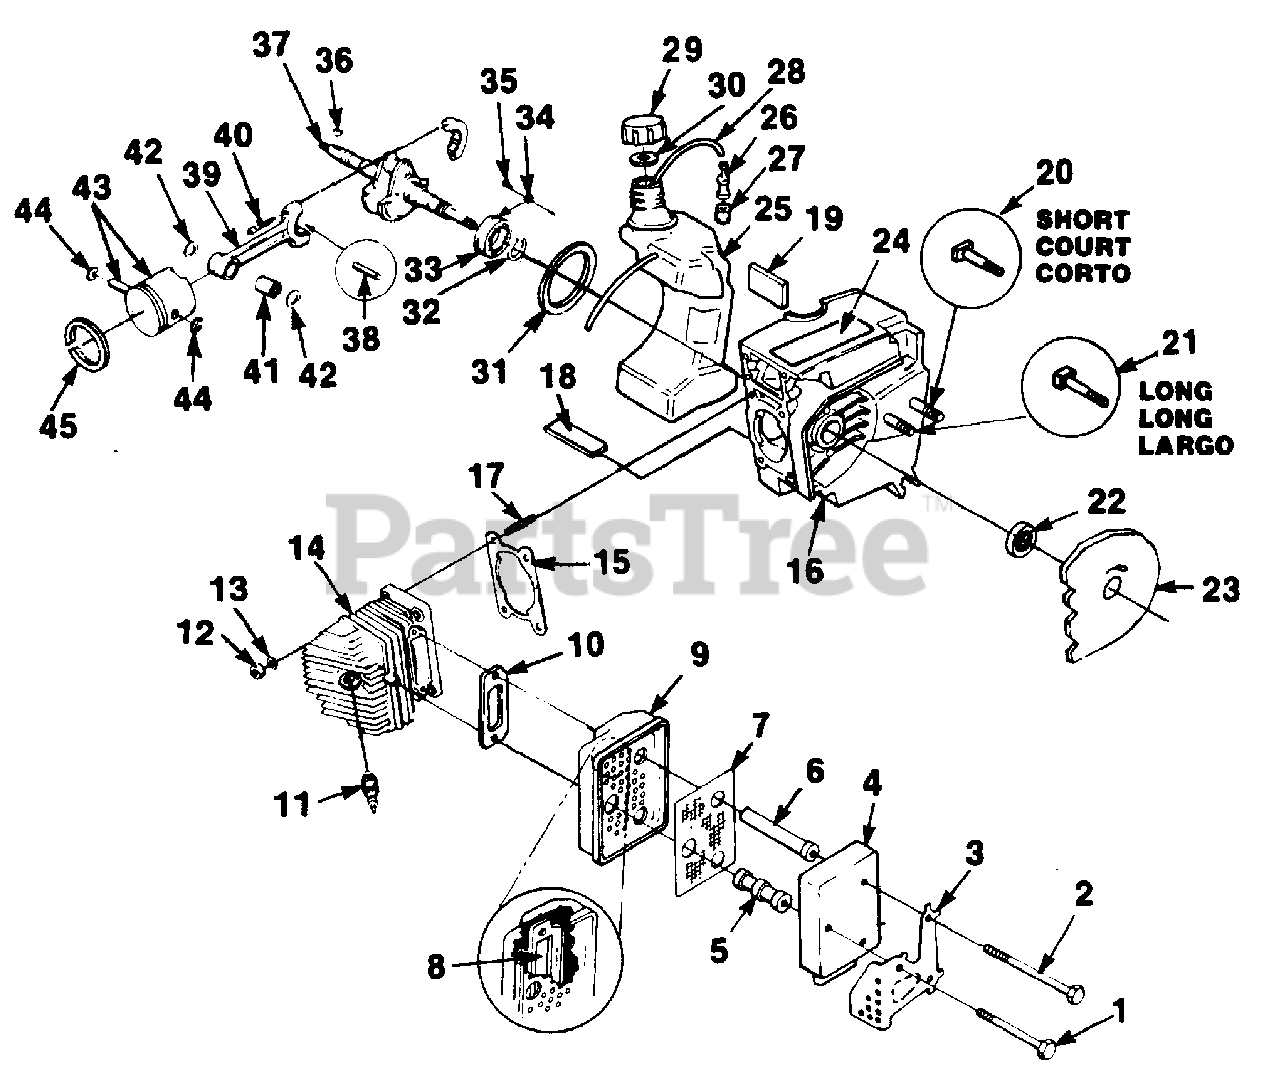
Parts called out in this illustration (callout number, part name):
1	SCREW- Hex hd.
2	SCREW- Hex hd. (1/4-20 x 3")
3	SHIELD- Muffler
4	CAP- Muffler
5	SUPPORT- Short
6	SUPPORT- Long
7	SCREEN- Spark arrestor
8	PLATE- Muffler
9	BODY- Muffler
10	GASKET- Muffler
11	SPARK PLUG
12	NUT- (1/4-28 x 3/8")
13	WASHER- Lock
14	CYLINDER
15	GASKET- Cylinder
16	CRANKCASE
17	STUD- Cylinder
18	SPACER- Fuel tank
19	SPACER- Fuel tank
20	BOLT- (3/8-16 x 2 1/8")
21	BOLT- (3/8-16 x 2 11/32")
23	SAW DUST SHIELD
24	DECAL- Instruction/Warning
25	FUEL TANK
26	FILTER- Fuel
27	ELEMENT- Filter
28	TUBING- Rubber (13")
29	CAP- Fuel
30	GASKET- Fuel cap
31	"O" RING
32	RING- Retaining
33	BEARING- Ball
34	WASHER- Lock
35	SCREW- Torx (10-32)
36	KEY- Woodruff
37	CRANKSHAFT
38	BEARING- Needle
39	ROD- Connecting
40	SCREW- Hex hd. (8/32 x 1/2")
41	BEARING
43	PISTON & PIN ASSY.
44	RING- Retaining
45	PISTON RING
